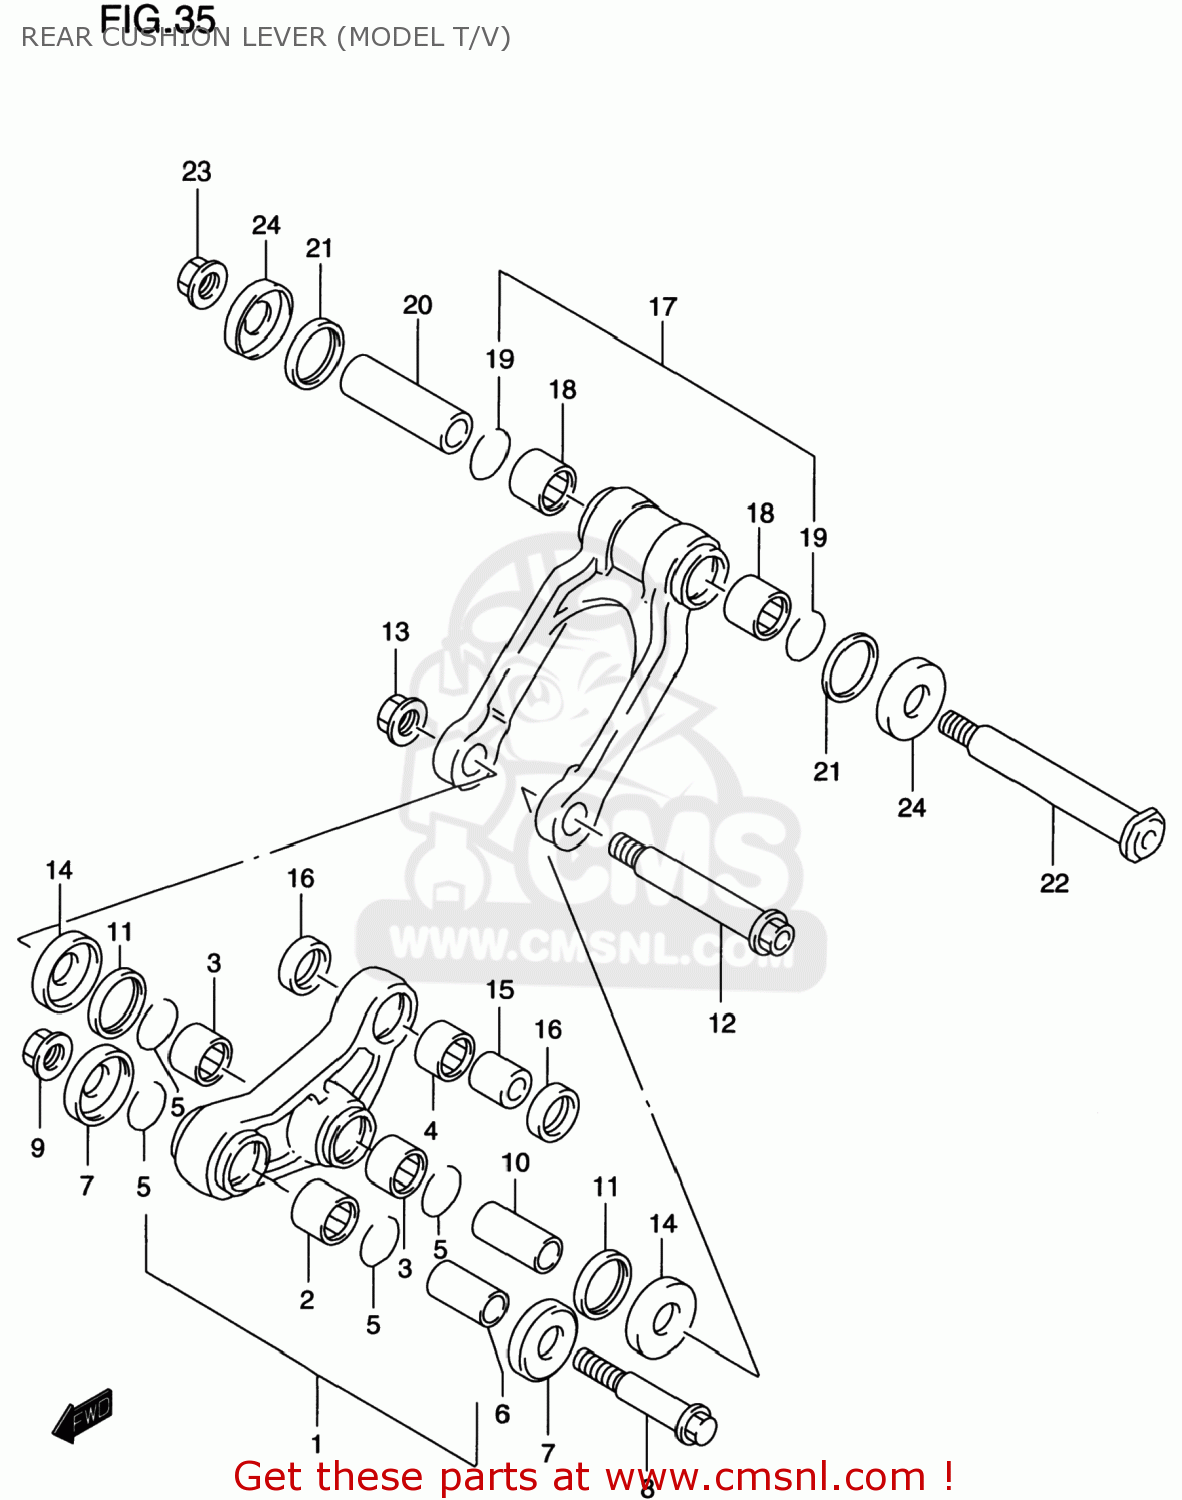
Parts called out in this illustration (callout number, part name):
1	LEVER SET,RR CUSHION
2	BEARING(20X27X25)
3	BEARING(22X28X20)
4	BEARING(20X26X12)
5	CIRCLIP
6	SPACER,RR CUSHION LEVER FR
7	SEAL,RR CUSHION LEVER FR DUST
8	BOLT,RR CUSHION LEVER FR
9	NUT 12MM
10	SPACER,RR CUSHION LEVER CTR
11	SEAL,RR CUSHION LEVER CTR
12	BOLT,RR CUSHION LEVER CTR
13	NUT
14	CAP,RR CUSHION LEVER CTR
15	SPACER,RR CUSHION LEVER RR
16	SEAL,OIL(20X26X4.5)
17	LEVER SET,REAR CUSHION
18	BEARING(22X28X20)
19	CIRCLIP
20	SPACER,RR CUSHION ROD
21	SEAL,RR CUSHION LEVER CTR
22	BOLT,RR CUSHION ROD
23	NUT
24	CAP,RR CUSHION LEVER CTR
